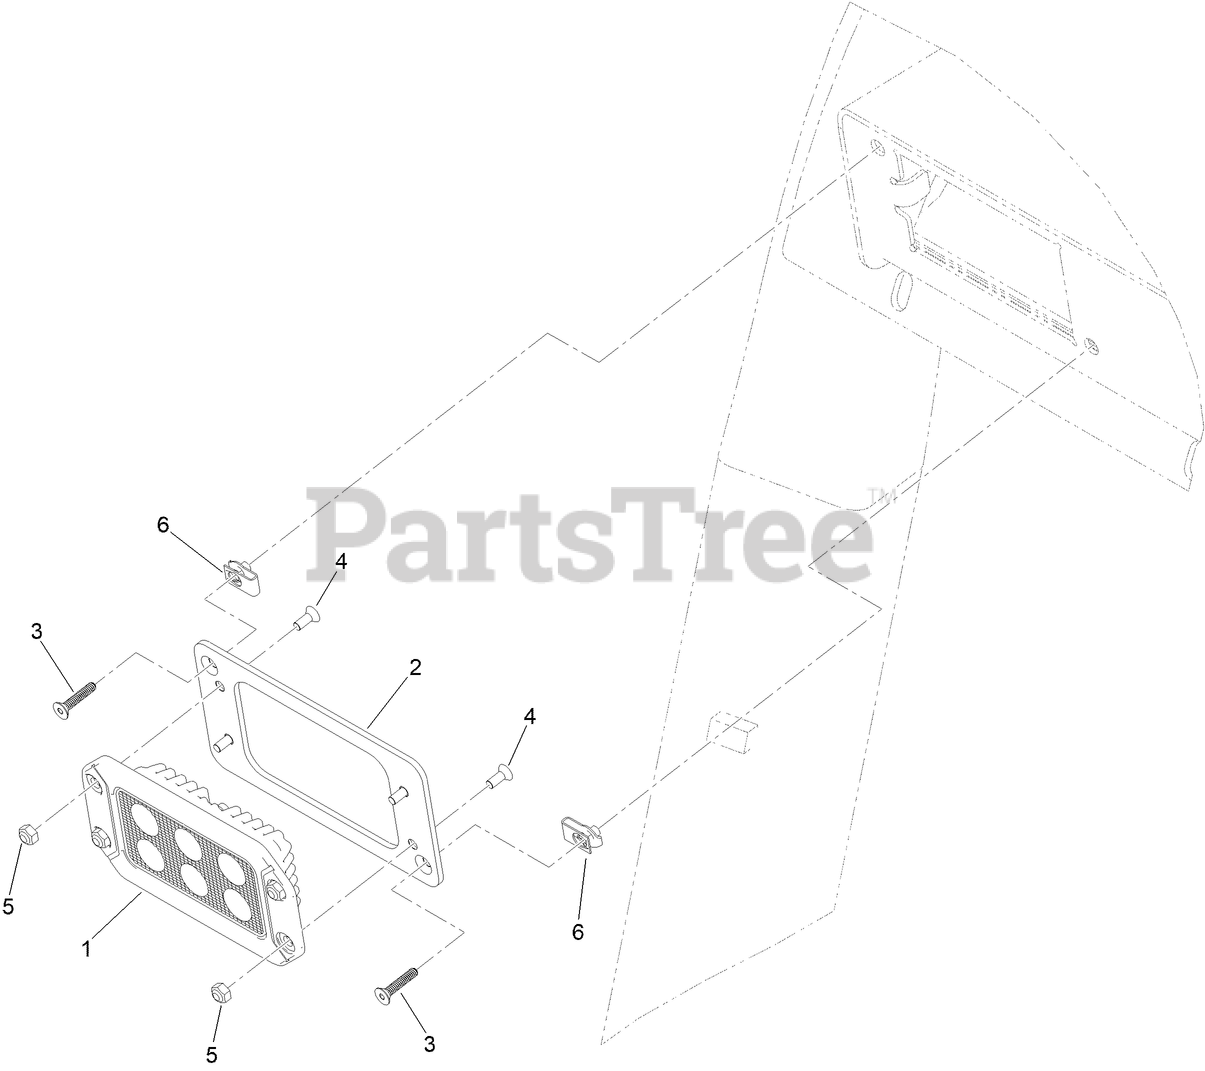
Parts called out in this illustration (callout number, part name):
1	LIGHT-WORK,FLUSH LED
2	PLATE - ADAPTER
3	SCREW FLAT HD #10-24X1.00
4	SCREW-HSFH
5	NUT-LOCK, NI
6	NUT,10-24, (J) CAGE, BLK**KIT MSC05077*
